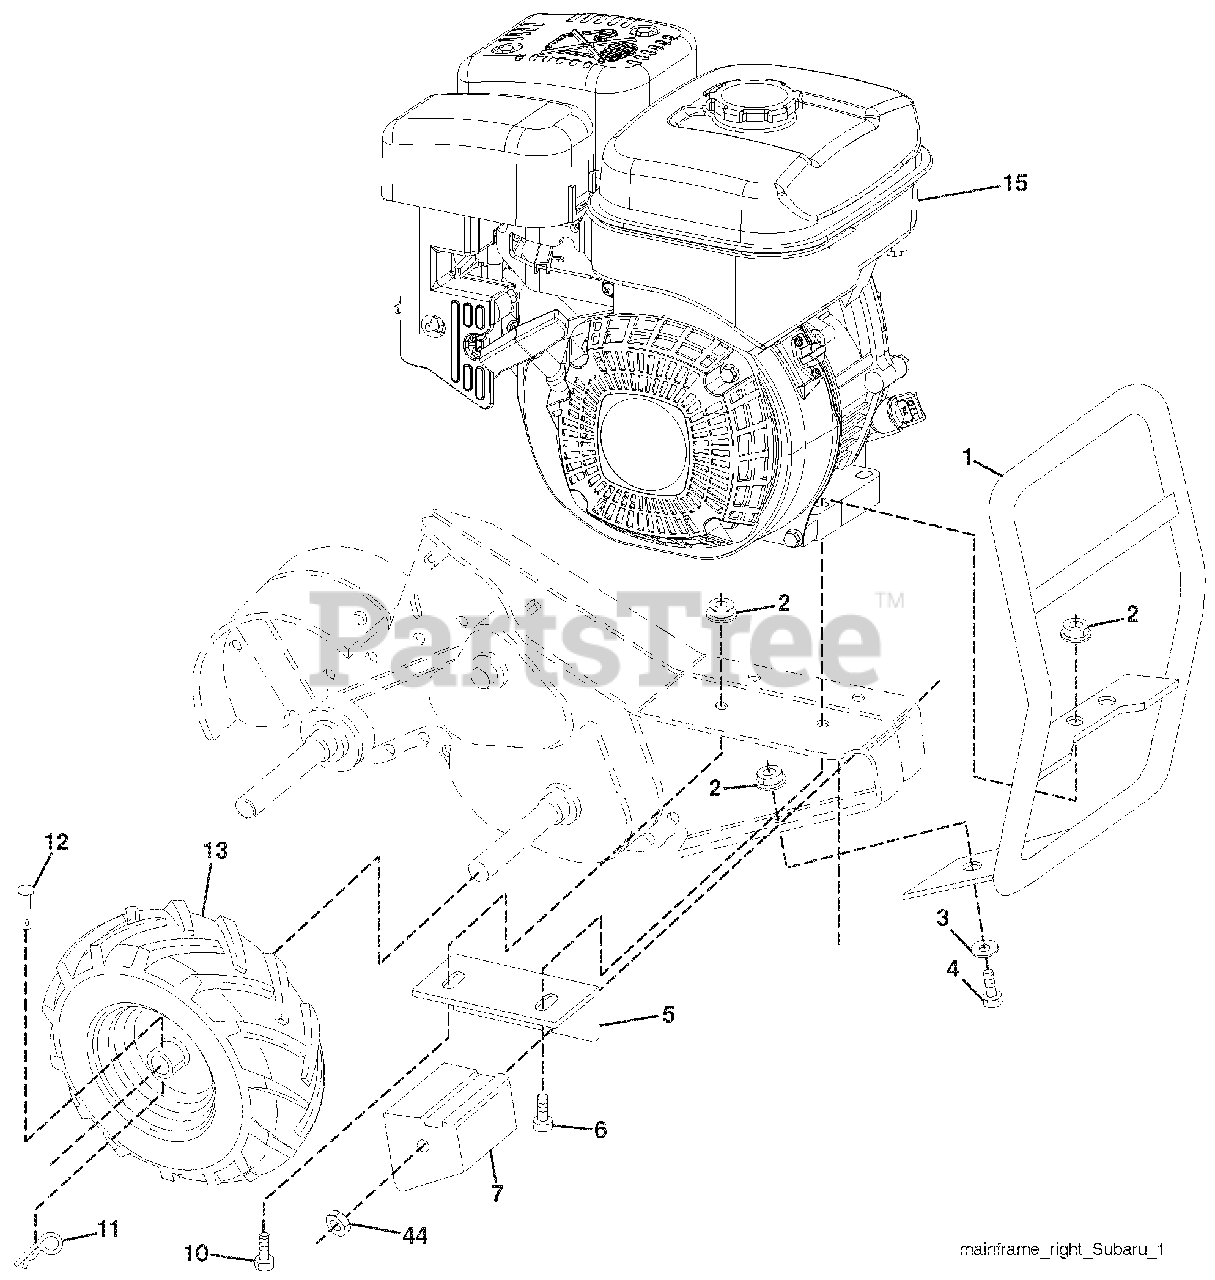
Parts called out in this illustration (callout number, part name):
2	Nut, Hex, Flangelock
3	Washer 11/32 x 11/16 x 16 Ga.
4	Bolt, Hex Head 5/16-18 x 3/4
5	Bracket, Reinforcement
6	Bolt, Fin Hex 5/16-18 unc x 1-
7	COUNTERWEIGHT, RH
10	Bolt, Hex Head, Gr. 25/16-18 x
11	Retainer Spring
12	Rivet, Drilled
13	TIRE AND WHEEL ASSEMBLY
15	ENGINE SUBARU MDL# EX170DT1031
44	Nut, Hex, Crownlock 3/8-16
